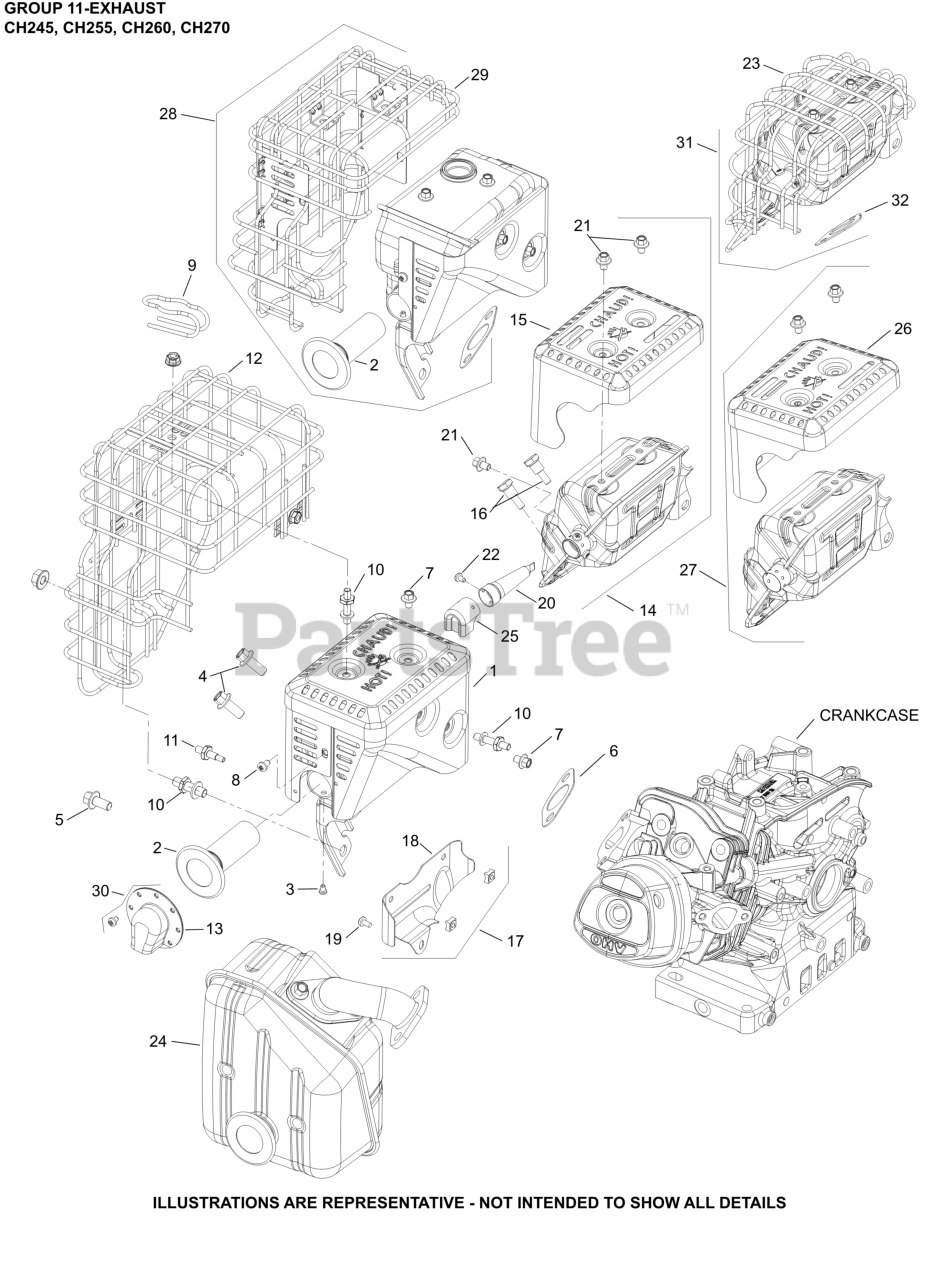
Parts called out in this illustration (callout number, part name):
1	KIT, MUFFLER
2	ARRESTOR ASSEMBLY, SPARK
3	SCREW, SPARK ARRESTOR
4	SCREW, M8 X 20
6	GASKET, MUFFLER
8	SCREW, M5 X 8
